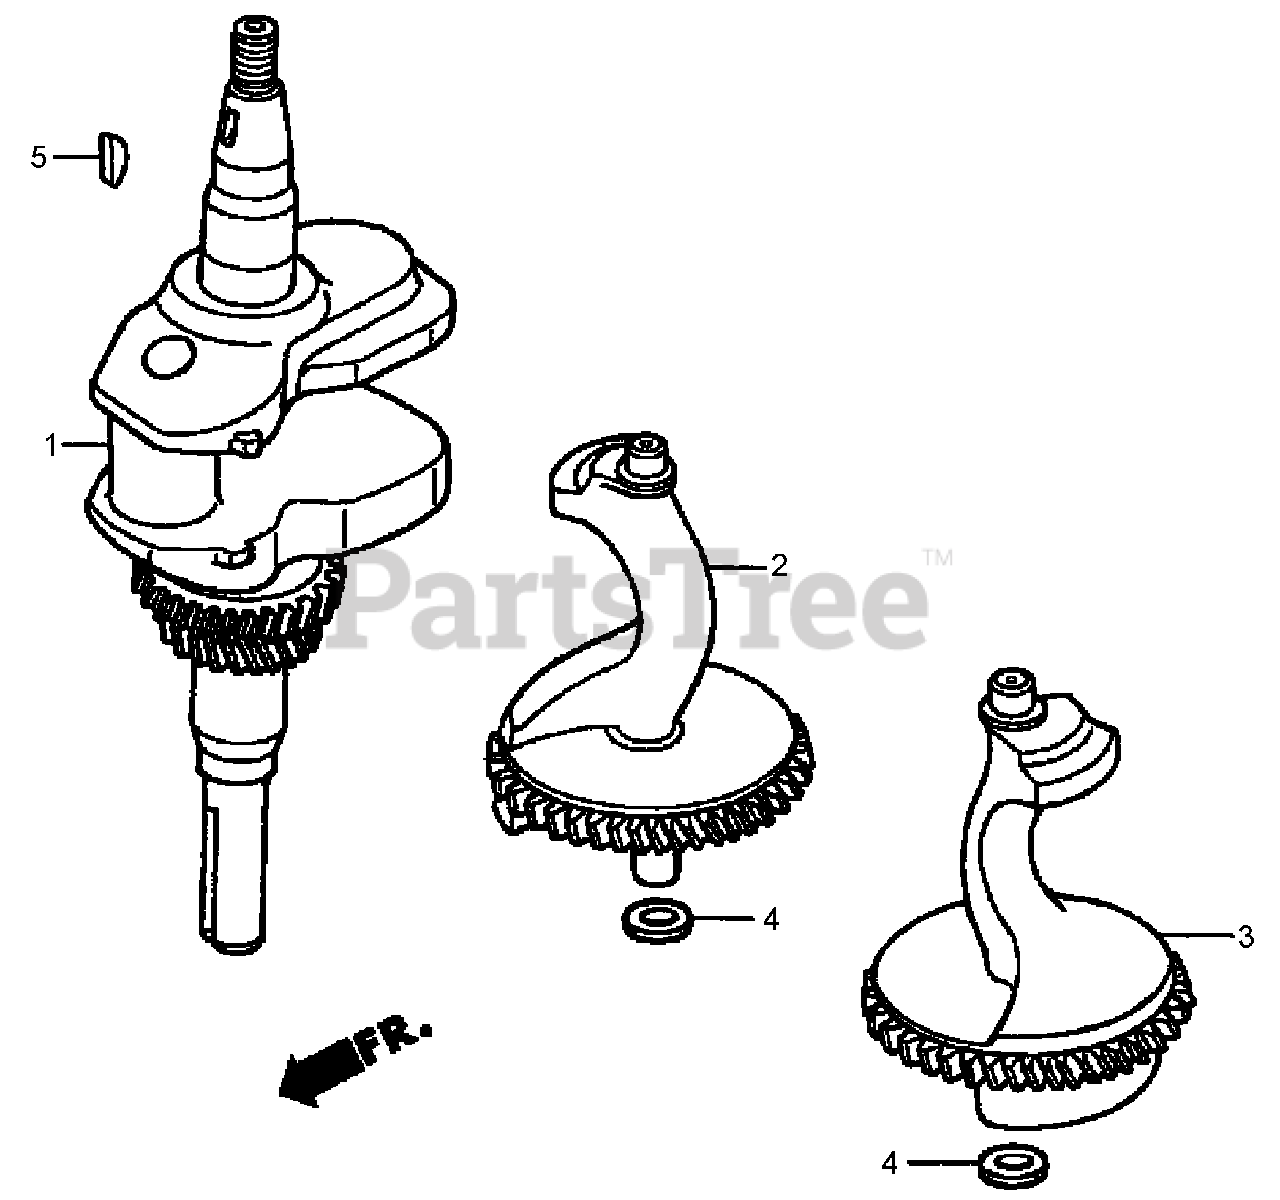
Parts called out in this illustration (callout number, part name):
1	CRANKSHAFT
2	BALANCER-WEIGHT A
3	BALANCER-WEIGHT B
4	WASHER-THRUST (14MM)
5	KEY-WOODRUFF, SPECIAL (25X18)
